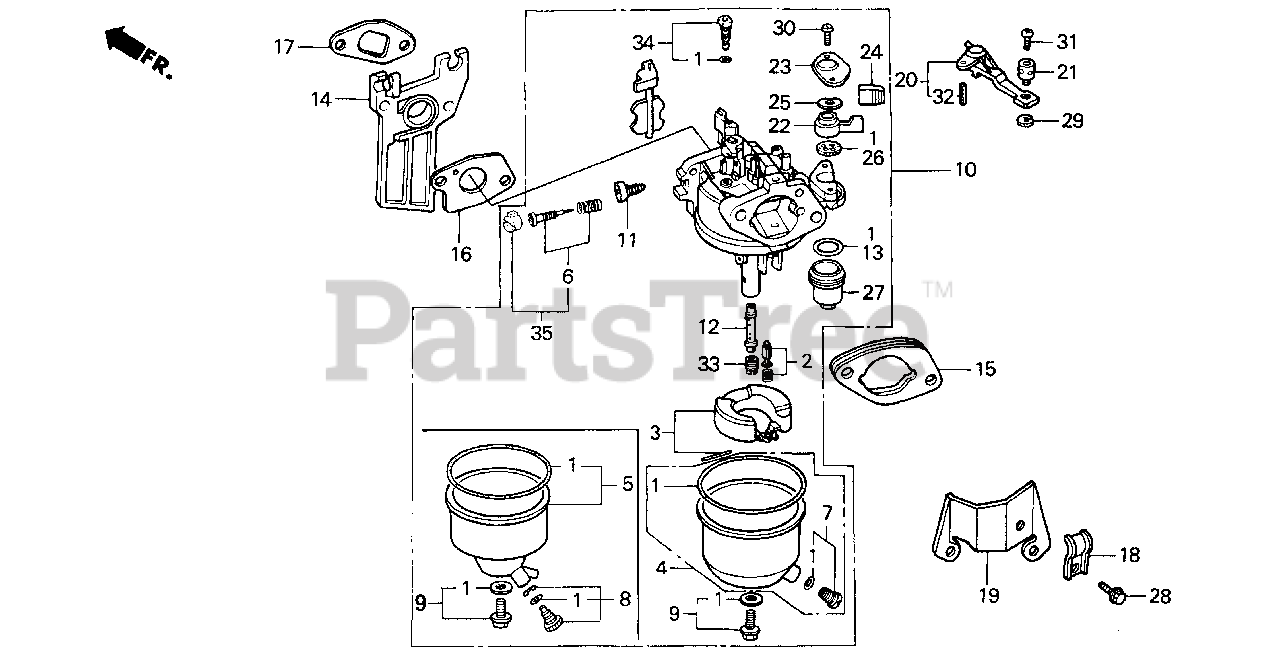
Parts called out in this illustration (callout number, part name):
1	GASKET SET
2	VALVE SET, FLOAT
5	CHAMBER SET, FLOAT
6	SCREW SET, PILOT
8	SCREW SET, DRAIN
9	SCREW SET B
10	CARBURETOR ASSY. (BE07D B)
10	CARBURETOR ASSY. (BE65L A)
11	SCREW, THROTTLE STOP
12	NOZZLE, MAIN
13	GASKET, FUEL STRAINER CUP
14	INSULATOR, CARBURETOR
15	SPACER, CARBURETOR
16	GASKET, CARBURETOR
17	GASKET, INSULATOR
20	LEVER, CHOKE (REMOTE)
22	LEVER, VALVE
23	PLATE, LEVER SETTING
24	CAP, LEVER
25	SPRING, VALVE LEVER
26	GASKET, VALVE
27	CUP, FUEL STRAINER
30	SCREW, PAN (3X6)
32	PIN, SPRING (2X12)
33	JET, MAIN (#70)
33	JET, MAIN (#72)
33	JET, MAIN (#75)
34	JET SET, PILOT (#35)
35	SCREW SET
